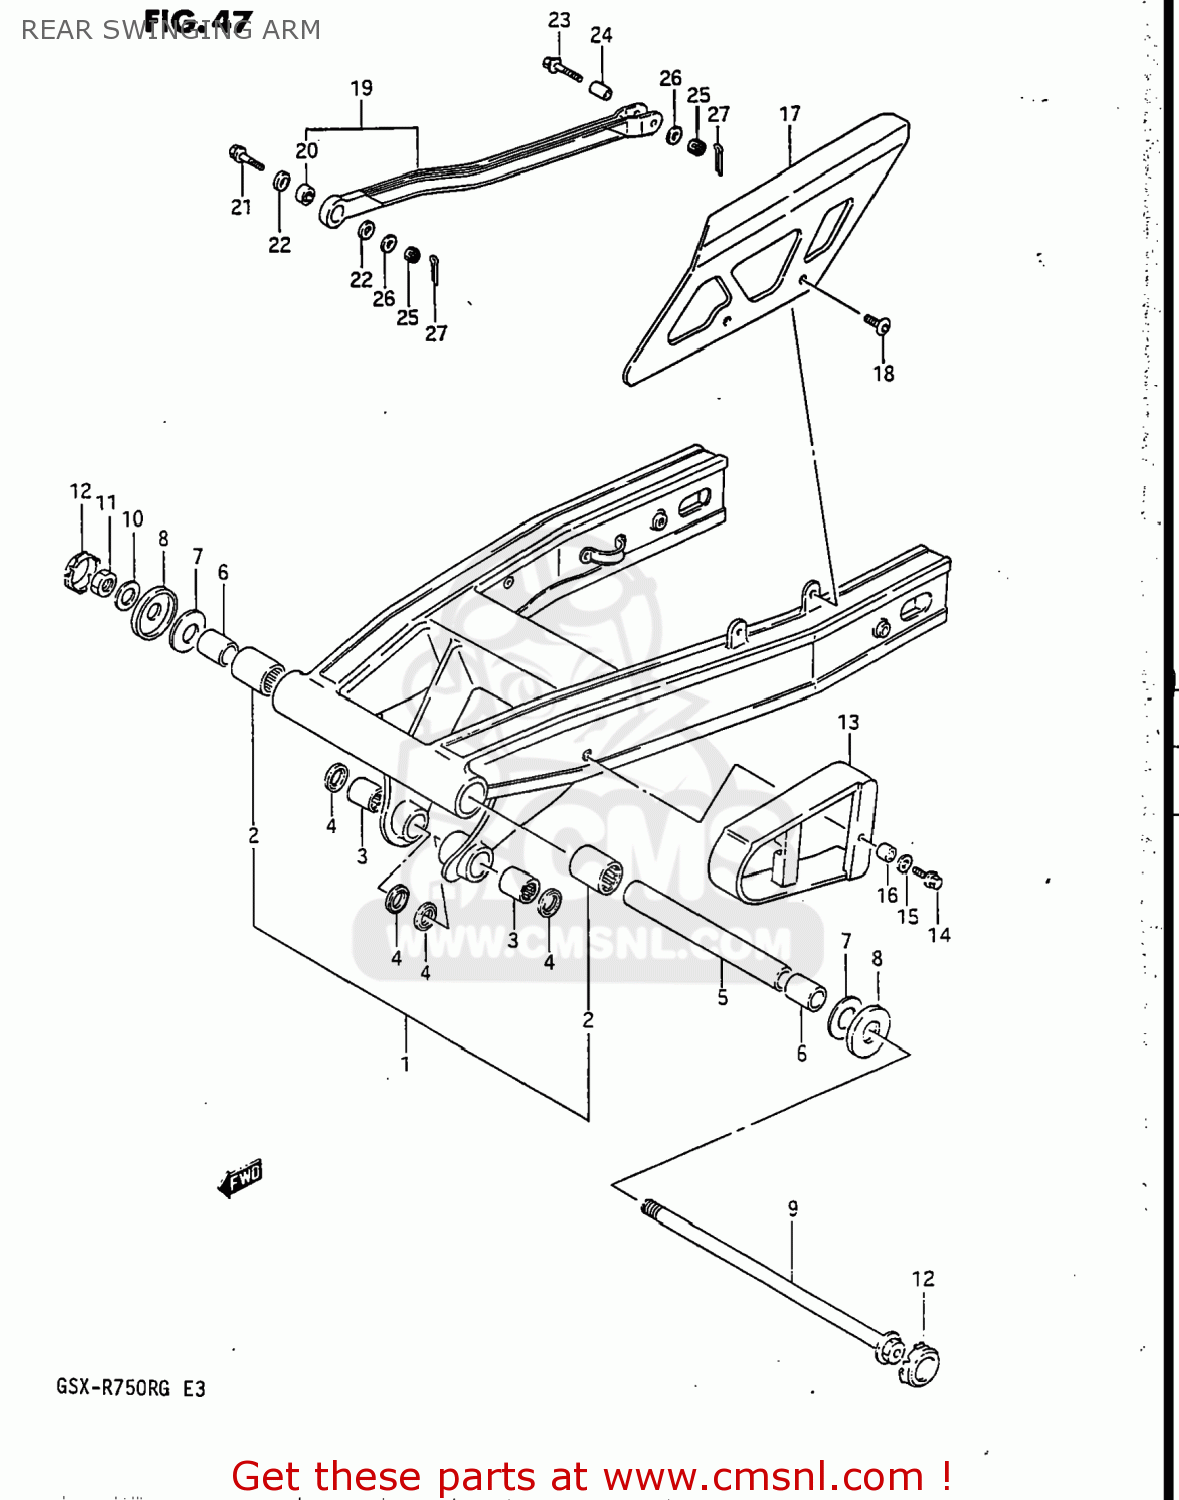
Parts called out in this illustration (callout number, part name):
1	SWING ARM ASSEMBLY,REAR
2	BEARING(22X29X25)
3	ROLLER BEARING (17X24X25))
4	SPACER,REAR CUSHION ROD
5	SPACER,RR SWGARM PIVOT CTR
6	SPACER,RR SWGARM PIVOT BEARING
7	WASHER
8	COVER,RR SWGARM DUST SEAL
9	SHAFT,REAR SWING ARM
10	WASHER(14X27X3)
11	NUT
12	CAP,SWINGINGARM PIVOT
13	BUFFER,CHAIN TOUCH DEFENSE
14	BOLT,M6X1X20
15	WASHER(6.5X16X1.2)
16	SPACER(6.5X8.5X5.8)
17	CASE,CHAIN
18	SCREW(6X12)
19	TORQUE LINK SET,REAR
20	SPHERICAL BEARING,TORQUE
21	BOLT(8X38)
22	23
23	BOLT
24	SPACER,RR TORQUE LINK RR
25	NUT 8MM
26	WASHER
27	PIN 20X20
